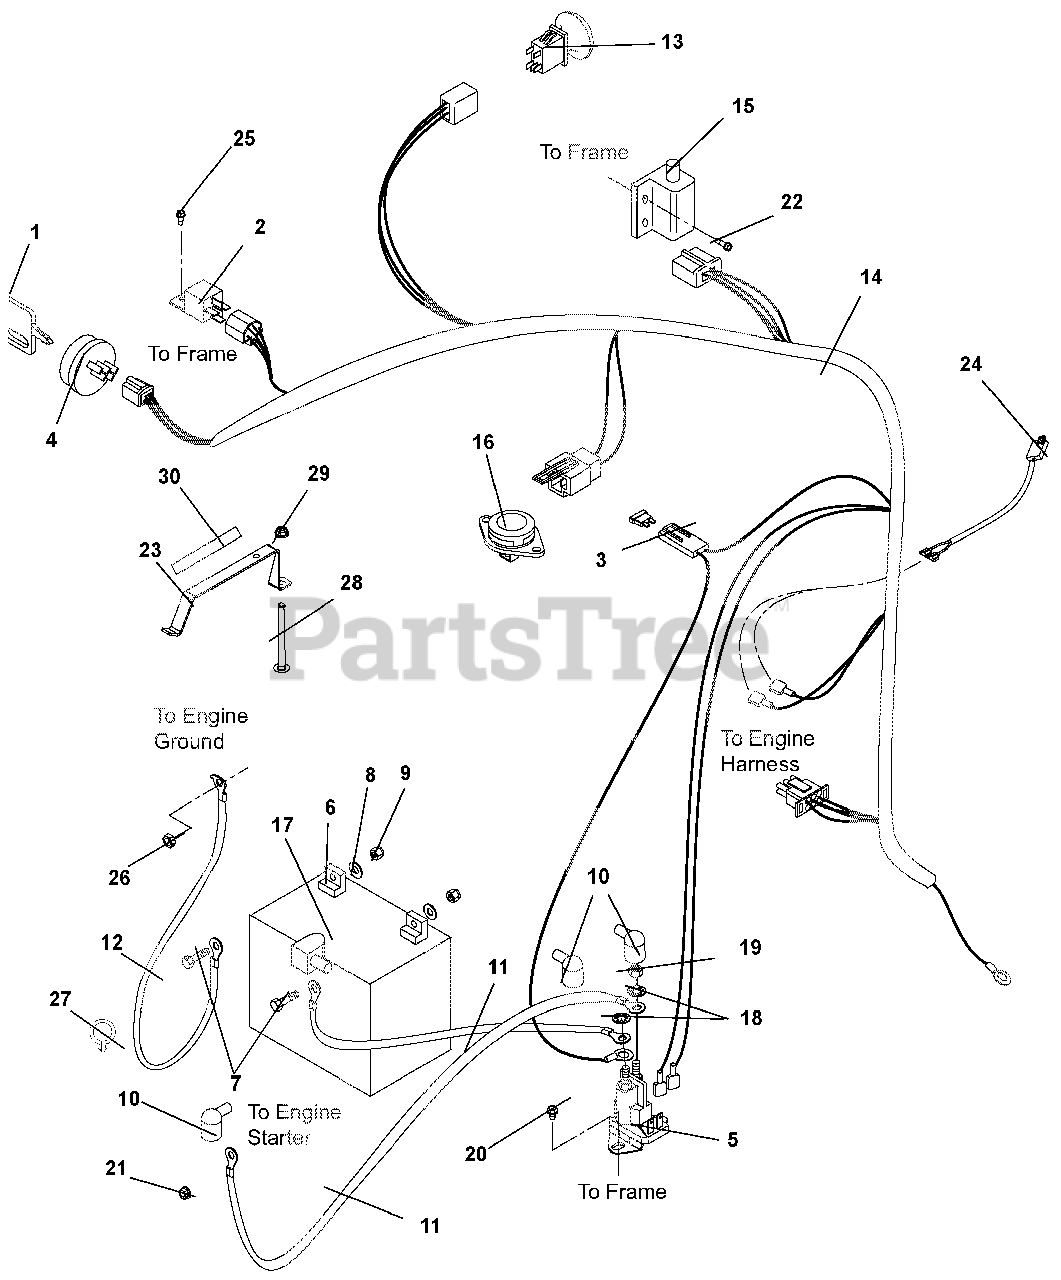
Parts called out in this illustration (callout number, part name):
1	KEY, 03290500 KEYSWITCH
2	RELAY
3	FUSE-25 AMP ATC TYPE
4	KEYSWITCH-IGNITION 3 POS
5	SOLENOID, STARTER (SEALED)
6	BATTERY, 12V 12A-190CCA
7	@BLT-HEX .25-20X.75 GR5 YWZC
8	@WSHR-FL-STL.281X.62X.065 YWZC
9	NUT-KEPS .250-20
10	BOOT, EYELET TERMINAL
11	CABLE,POS W/2 1/4 RING 15.0 LG
12	CABLE, NEGATIVE 26" 6 GA.
13	SWITCH, CLUTCH (YELLOW)
14	HARNESS, ZOOM/ZT WIRE
15	SWITCH- DOUBLE POLE N.O./N.O.
16	SWITCH- SEAT
17	INSULATOR
18	@WSHR-LK-EXT.262X.502X.026YWZC
19	NUT-HEX M6X1.0 YWZC
20	@SCR-TAP .25-20X.37 HWH YWZ TR
21	@NUT-LK-TOP-FLG .25-20 YWZC
22	SCR- 12-14X.75 HX W/HD TEK ZC
23	HOLDDOWN, BATTERY, U1&190CCA
24	HARNESS, CLUTCH
25	@SCR-TAP 10-24X.50 HWH TR YWZC
26	@NUT-LK-CTR-JAM .375-16 YWZC
27	WIRE CLIP
28	@BLT-RDHDSQNK .25-20X4.50 G2YZ
29	@NUT-LK-NYL-FLG .25-20 YWZC
30	DECAL, U1 BATTERY REPLACEMENT
31	CABLE TIE LG 5-1/2
